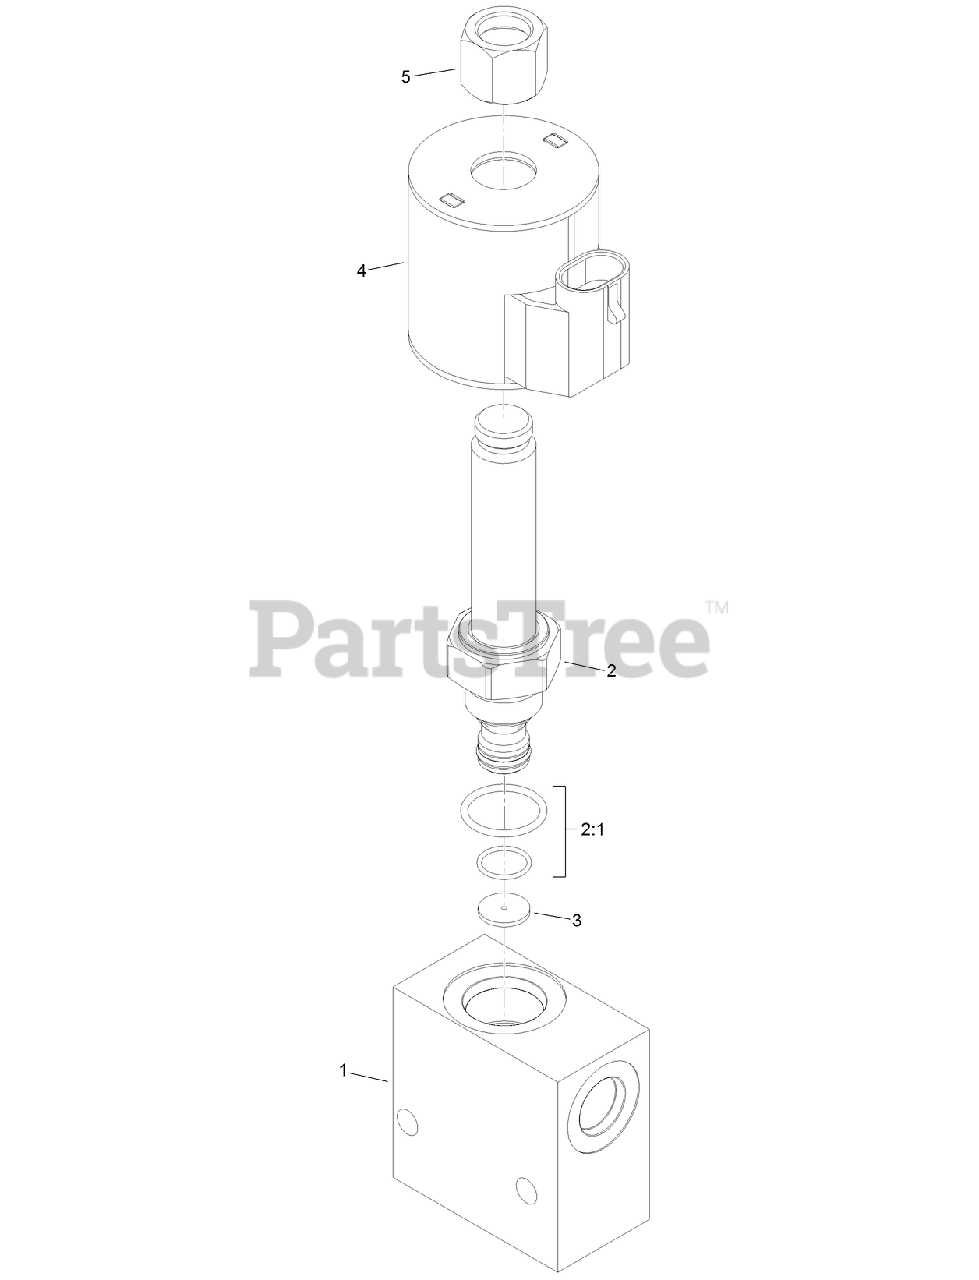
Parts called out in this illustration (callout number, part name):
1	BLOCK-MANIFOLD
2	VALVE-PRESSURE RELIEF, PROP
2:1	SEAL KIT
3	DISC-ORIFICE (.055)
4	COIL-12V, DC
5	NUT-COIL (9/16-24 UNEF-2B)
